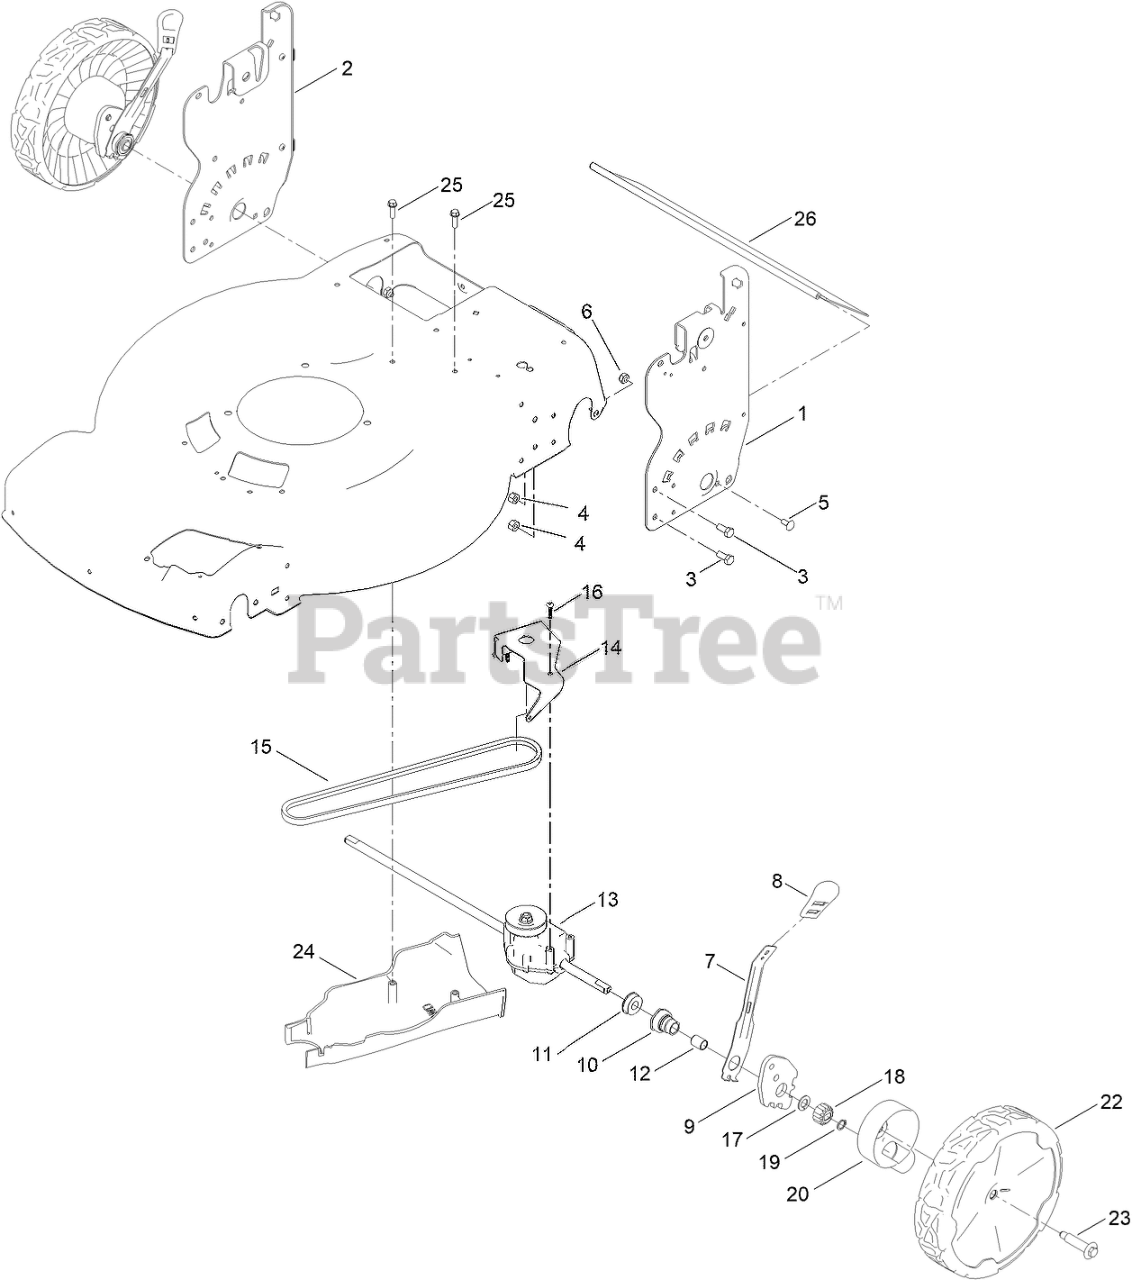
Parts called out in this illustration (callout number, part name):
1	PLATE-HOC, LH (ISO)
2	PLATE-HOC, RH (ISO)
3	SCREW-HH
4	NUT-LOCK, NI
5	SCREW-CARR
6	NUT-LOCK, NI
7	ARM-SPRING
8	KNOB-HOC
9	ARM-PIVOT, REAR
10	RETAINER-BUSHING, HOC
11	BEARING-BALL
12	BUSHING-SLEEVE
13	TRANSMISSION-RWD
14	BRACKET-TRANSMISSION
15	V-BELT
16	SCREW-PLASTITE
17	WASHER-THRUST
18	GEAR-PINION, 15T
19	RING-RETAINING
20	ASM-COVER, GEAR (DK GRAY)
22	ASM-9.65" WHEEL, GEARED
23	WHEEL BOLT
24	COVER-BELT, RWD
25	SCREW-HWH
26	SHIELD-TRAILING
